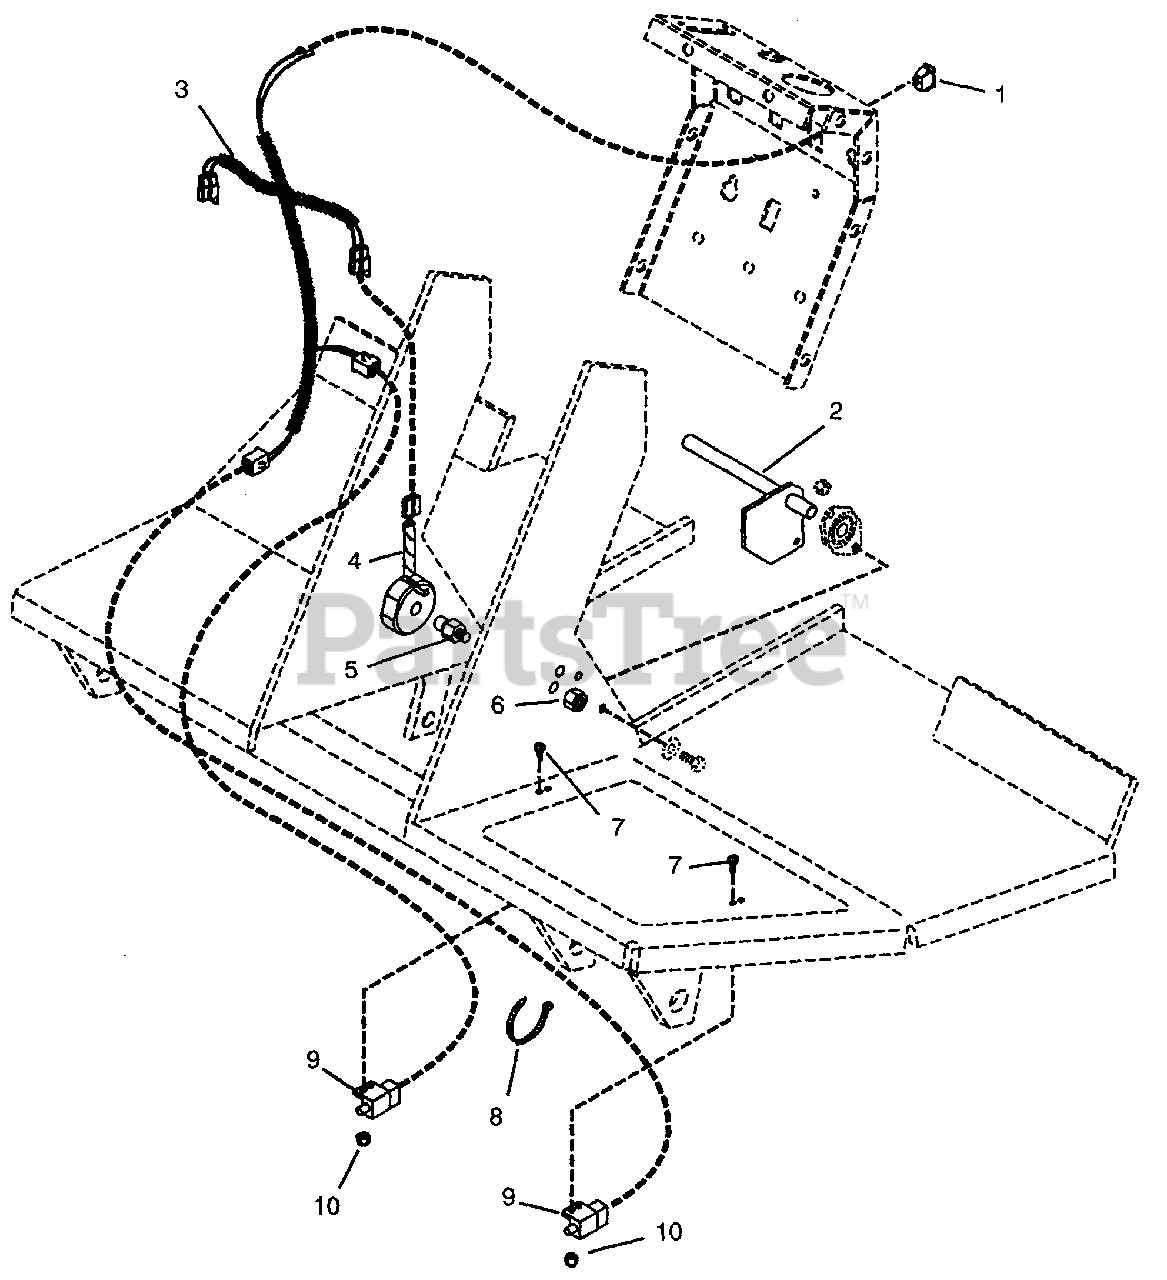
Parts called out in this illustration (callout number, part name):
1	Switch, Light
2	Weldment, Control
3	Harness, Wiring
4	Assembly, Magnet
5	Pin, Magnet
6	Nut-Locking-Center .50-13
7	Screw-Machine 10-24 x .75 Hex Washer Head
8	Tie Wrap, Black
9	Switch, Interlock
10	Nut-Locking-Nylon 10-24 with Insert
